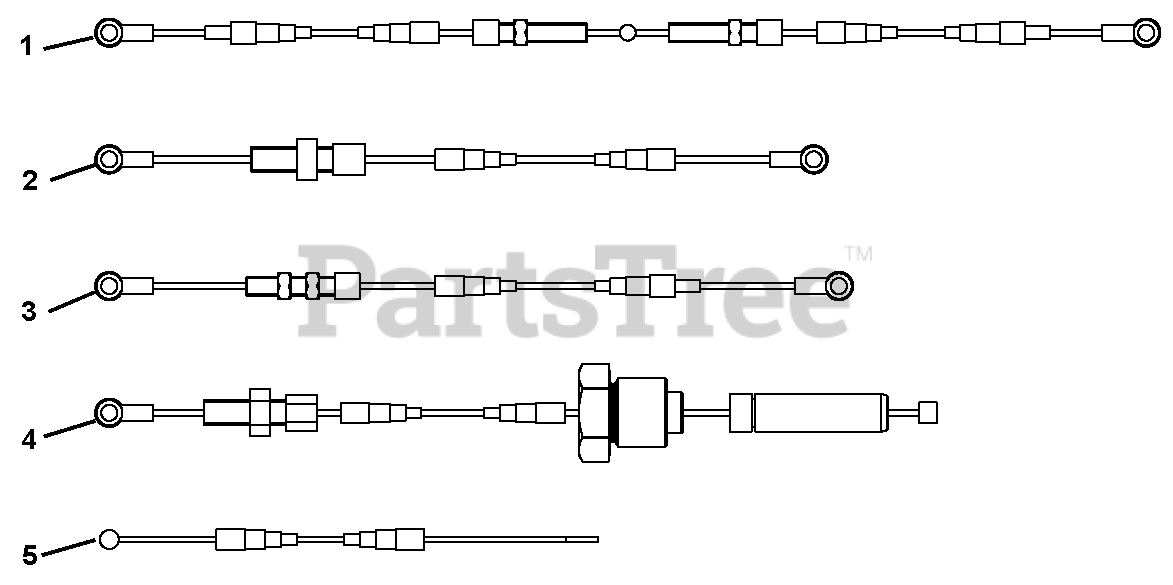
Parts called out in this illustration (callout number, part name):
1	Cable, Driving
2	Cable, Brake
3	Cable, Block
4	Cable, Swivelling Handlebar
5	Cable, Gas
